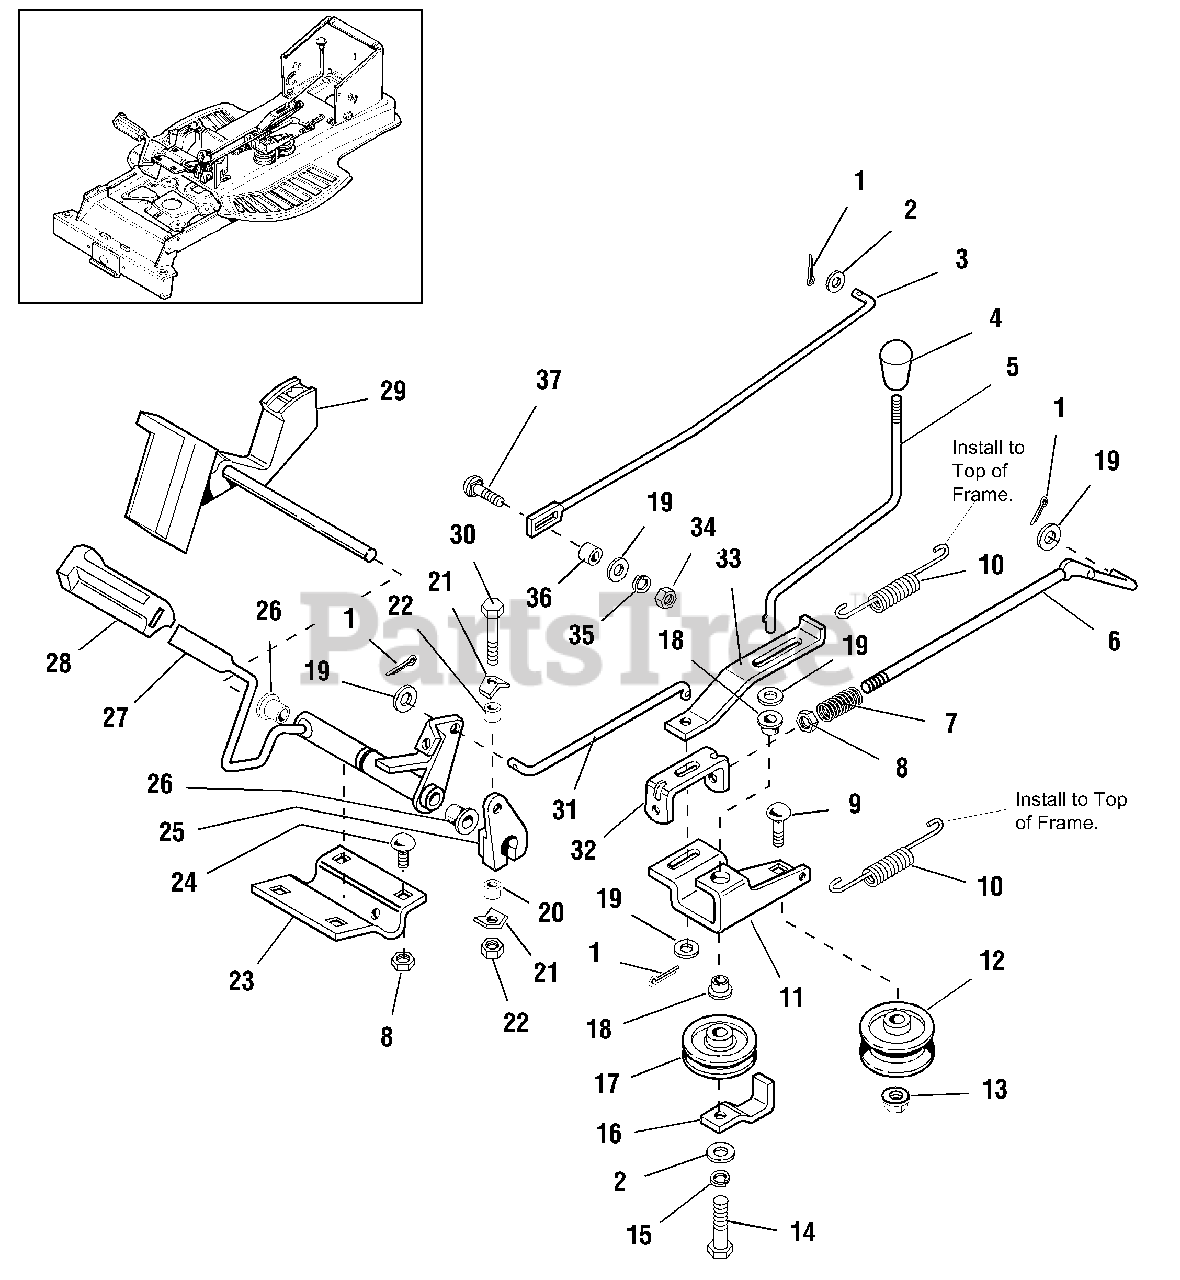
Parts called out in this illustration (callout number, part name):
1	PIN, Cotter, 3/32 x 3/4
2	WASHER, Plain, 3/8
3	ROD, Control
4	KNOB, Plastic, Parking Brake
5	ROD, Parking Brake
7	SPRING, Brake Rod
8	NUT, Hex, Nylon Lock, 5/16-18
9	CARRIAGE BOLT, 3/8-16 x 1-3/4
10	SPRING, Idler
11	BRACKET, Idler
12	PULLEY, Backside
13	NUT, Hex, Flange Whiz, 3/8-16
14	CAPSCREW, 3/8-16 x 1-3/4
15	LOCKWASHER, 3/8
17	PULLEY, Idler, V
18	BUSHING, 5/8
19	WASHER, Plain, 5/16
22	NUT, Hex, Nylon Lock, 1/4-20
23	CLAMP, Tube
24	CARRIAGE BOLT, 5/16-18 x 3/4
25	LEVER, Hydro Control
26	BUSHING, Plastic
27	FOOT PEDAL ASSY.
28	PAD, Foot Pedal
29	PEDAL, Foot, Directional
30	CAPSCREW, 1/4-20 x 2-1/4
31	ROD, Clutch
32	GUIDE, Brake Rod
33	LEVER, Parking Brake
34	NUT, Hex, Full, 5/16-18
35	LOCKWASHER, 5/16
37	CARRIAGE BOLT, 5/16-18 x 1
